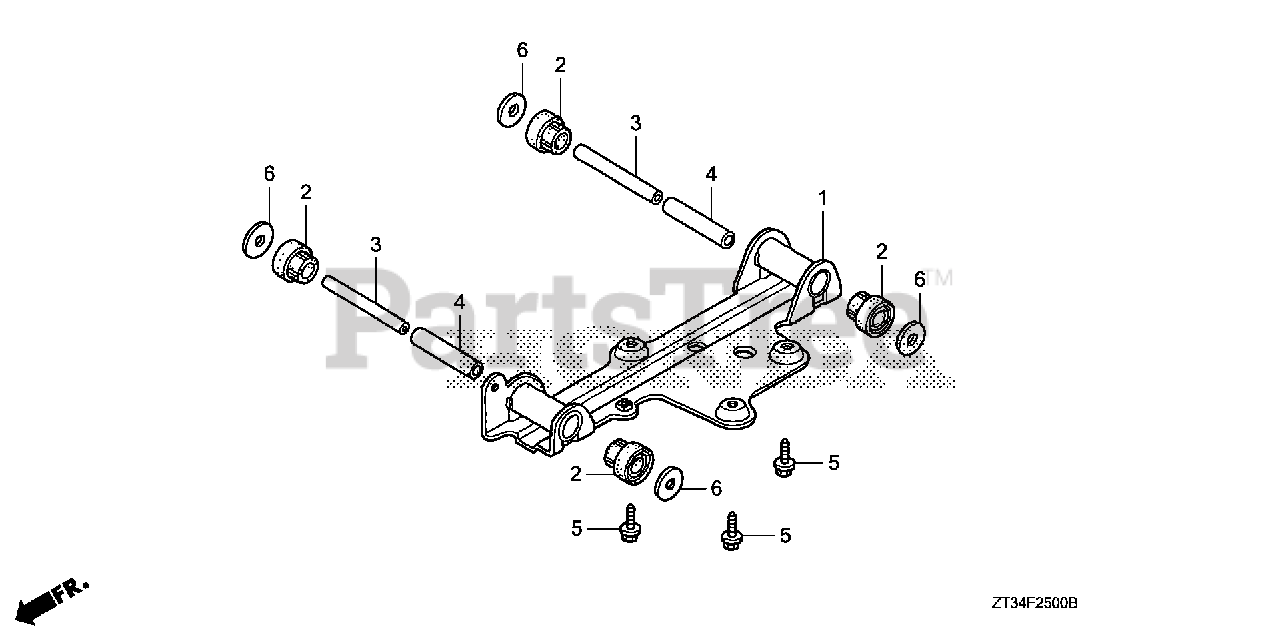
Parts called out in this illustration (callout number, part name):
1	BED, ENGINE
2	INSULATOR, ENGINE BED
3	COLLAR A, INSULATOR
4	COLLAR C, INSULATOR
5	BOLT, FLANGE (6X16) (CT200)
6	WASHER, SPROCKET SETTING
